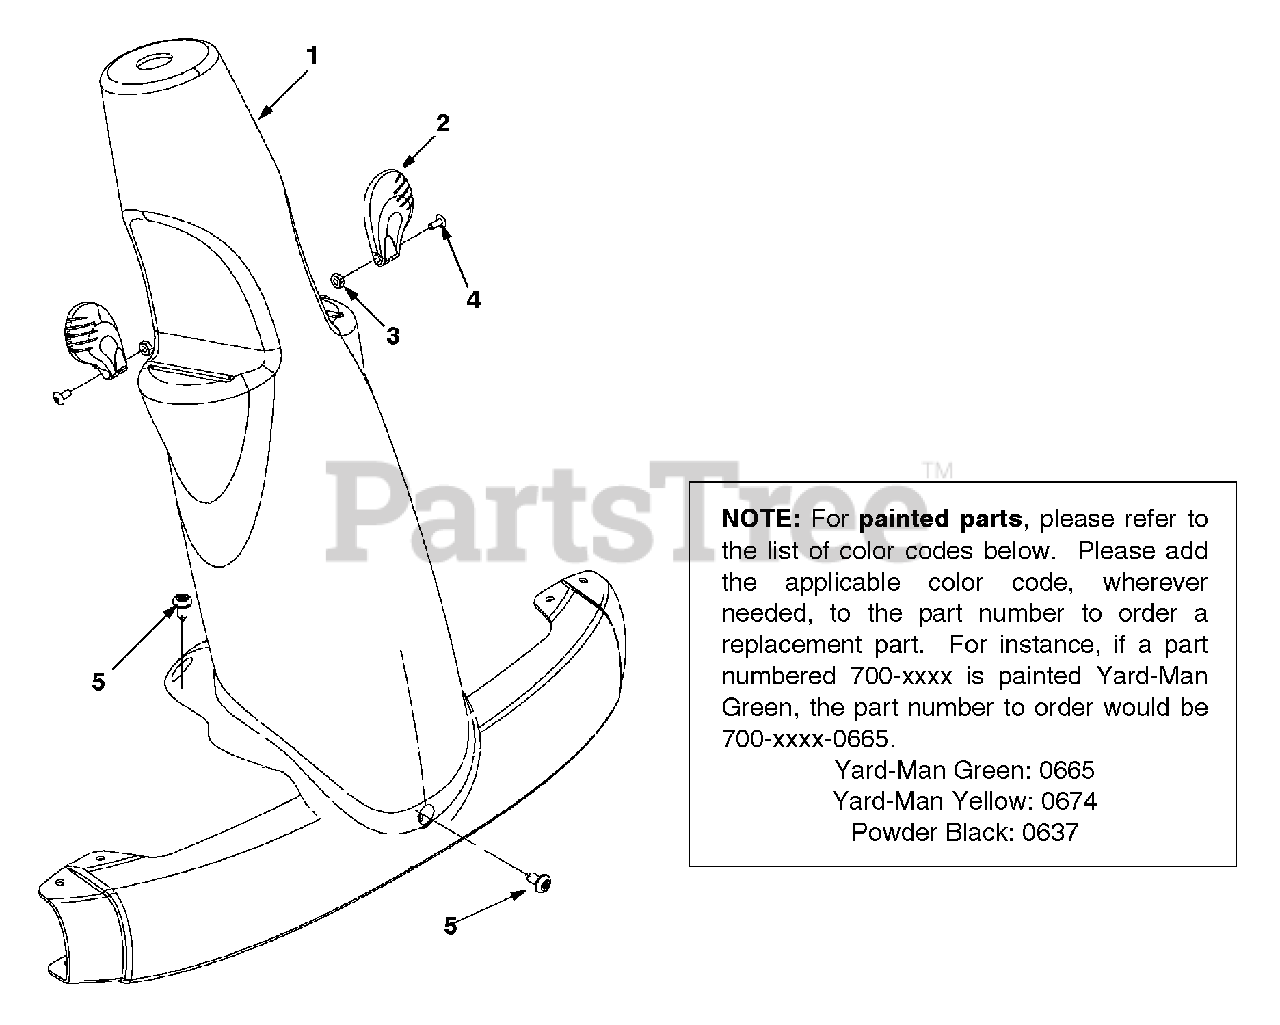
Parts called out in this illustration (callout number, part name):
1	Steering Column: Black
2	Control Knob
3	Hex Nut 8-32
4	Pan Head Machine Screw #8-32
5	Hex Screw TT 1/4-20 x .50"
